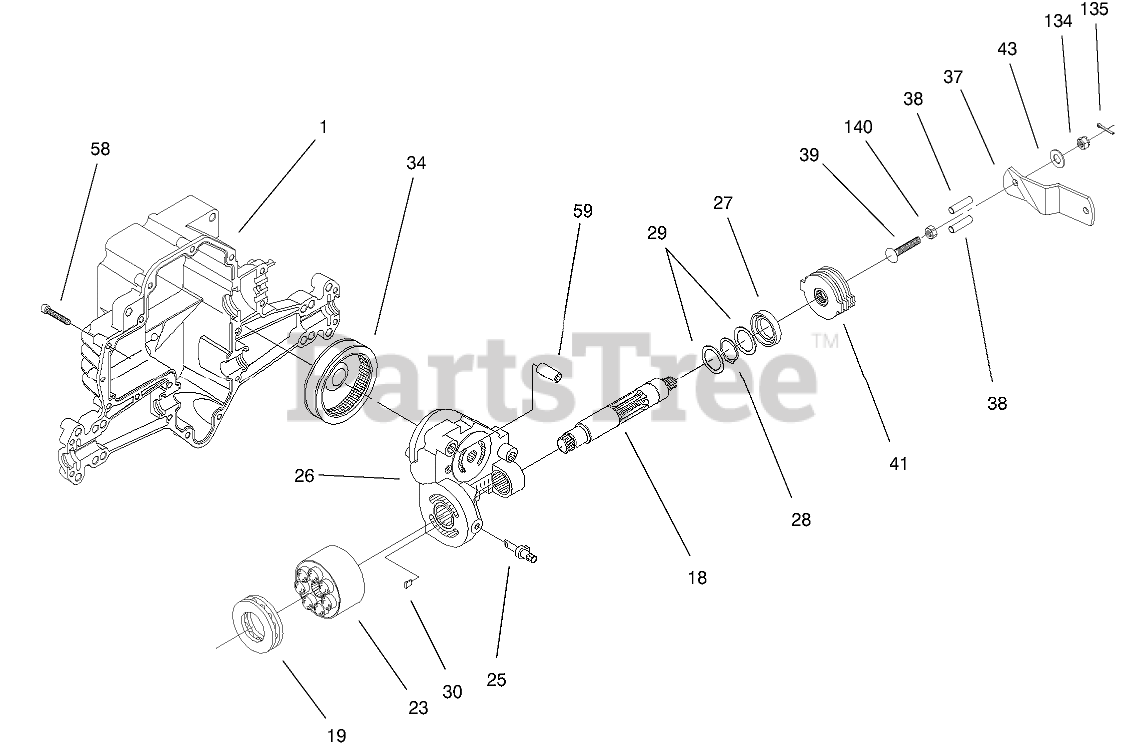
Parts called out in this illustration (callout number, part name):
1	HOUSING - LOWER
18	SHAFT - MOTOR
19	BEARING-THRUST
23	CYLINDER BLOCK ASM
25	ACTUATOR-BYPASS
26	Centersection ASM
27	SEAL - LIP
28	RING - RETAINING
29	WASHER
30	PLATE-BYPASS
34	ELEMENT - OIL FILTER
37	LEVER - BRAKE
38	PIN - ACTUATING
39	BOLT 5/16-18 X 1-3/4
41	KIT-BRAKE ROTOR/STATOR
43	WASHER-PIVOT
134	NUT-CASTLE
135	PIN-COTTER
140	NUT-LOCK, NI
